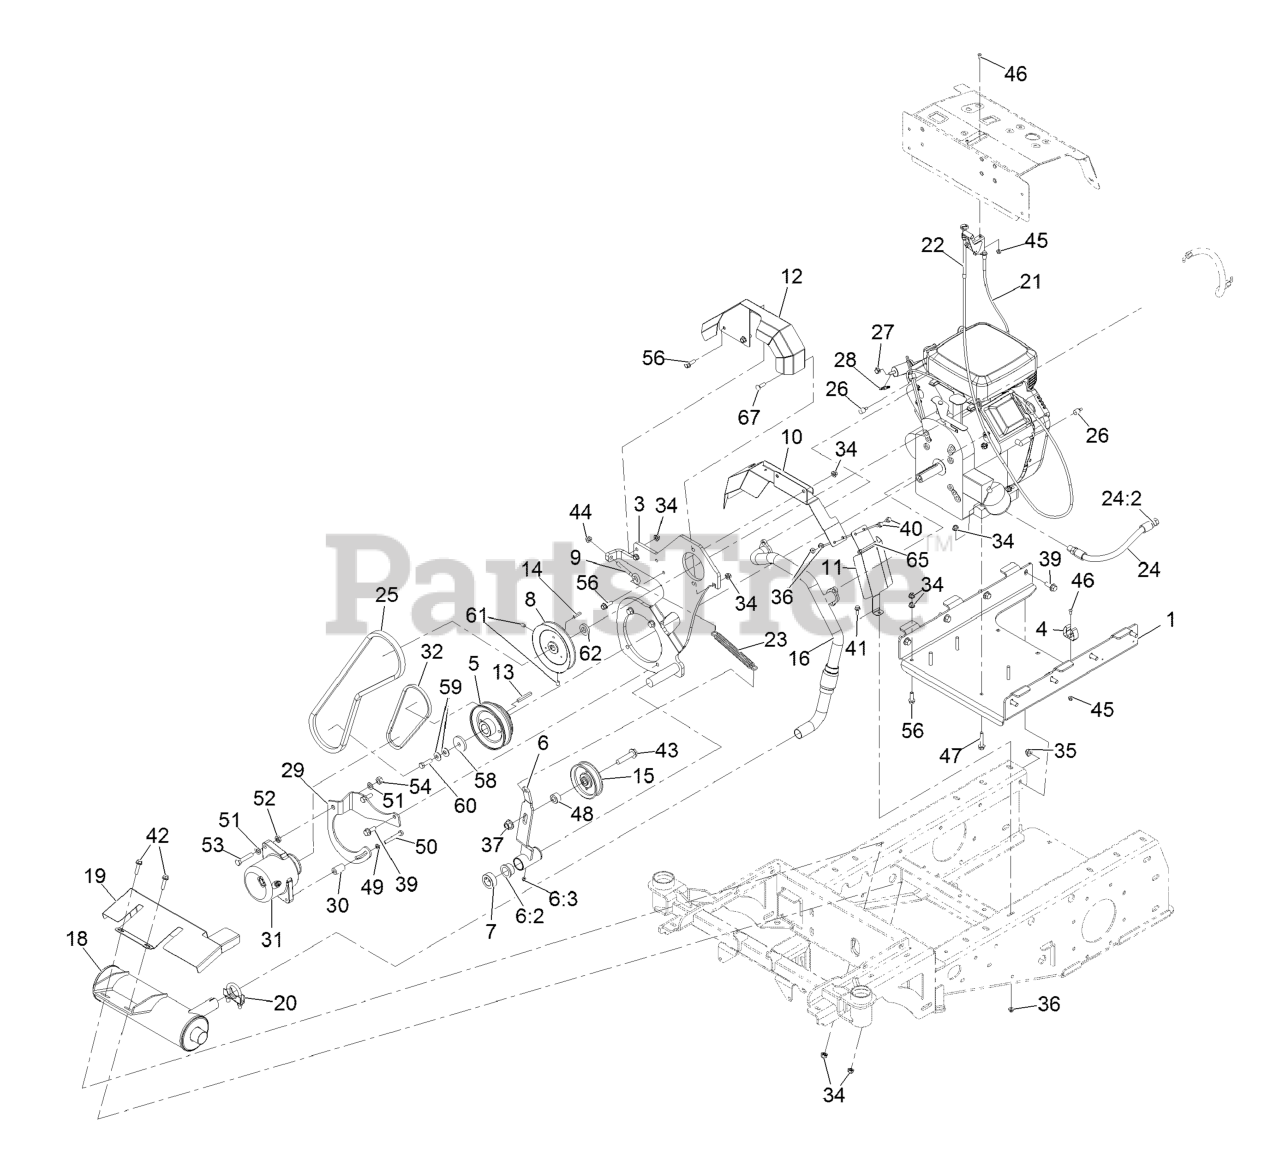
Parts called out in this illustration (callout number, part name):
1	Tray-Engine
3	Bracket-Engine, Pump [black]
4	Holder-Tool, Clip
5	Pulley-Double
6	Arm-Tension, ASM
6:2	BUSHING-FLANGE
6:3	FITTING-GREASE, ZERK
8	PULLEY-DRIVE, PUMP
9	Bolt-Eye
10	Guard, Lower Muffler
11	Guard, Lower Muffler
12	GUARD-PULLEY
15	PULLEY-IDLER, FLAT
16	MANIFOLD-EXHAUST
18	MUFFLER
19	SHIELD-HEAT, MUFFLER
20	Clamp-Muffler
21	CABLE-THROTTLE
22	CABLE-CHOKE
23	SPRING-EXTENSION
24	ASM, Oil Drain Hose W/Plug
26	Tube-Heat Shrink, 1/2
27	CLAMP-HOSE
28	Fitting-STR
29	Bracket-Alternator
30	TUBE-SUPPORT, ALTERNATOR
31	ALTERNATOR
32	Belt-V, 3L240
34	Nut-Hex Flange
35	Nut-Hex Flange
36	Nut-Hex Flange
37	Nut-Lock 1/2-13
39	SCREW-HHF
40	SCREW-HHF
41	Screw-HHF
42	SCREW-HHF
43	Screw-HHF
44	NUT-HF, NI
45	Nut-Hex Flange
46	Screw-HSBH
47	Screw-HHF
49	WASHER-LOCK
50	Screw-HH
51	Washer-Flat
52	Nut-Hex
53	Screw-HH
54	Nut-Lock, NI
56	SCREW-HHF
58	WASHER-PLAIN
59	WASHER-BELLEVILLE
60	Screw-HH
61	Setscrew-HSH
65	TIE-CABLE
67	Bolt,Carriage,5/16-18X1,ST/ST 18-8
